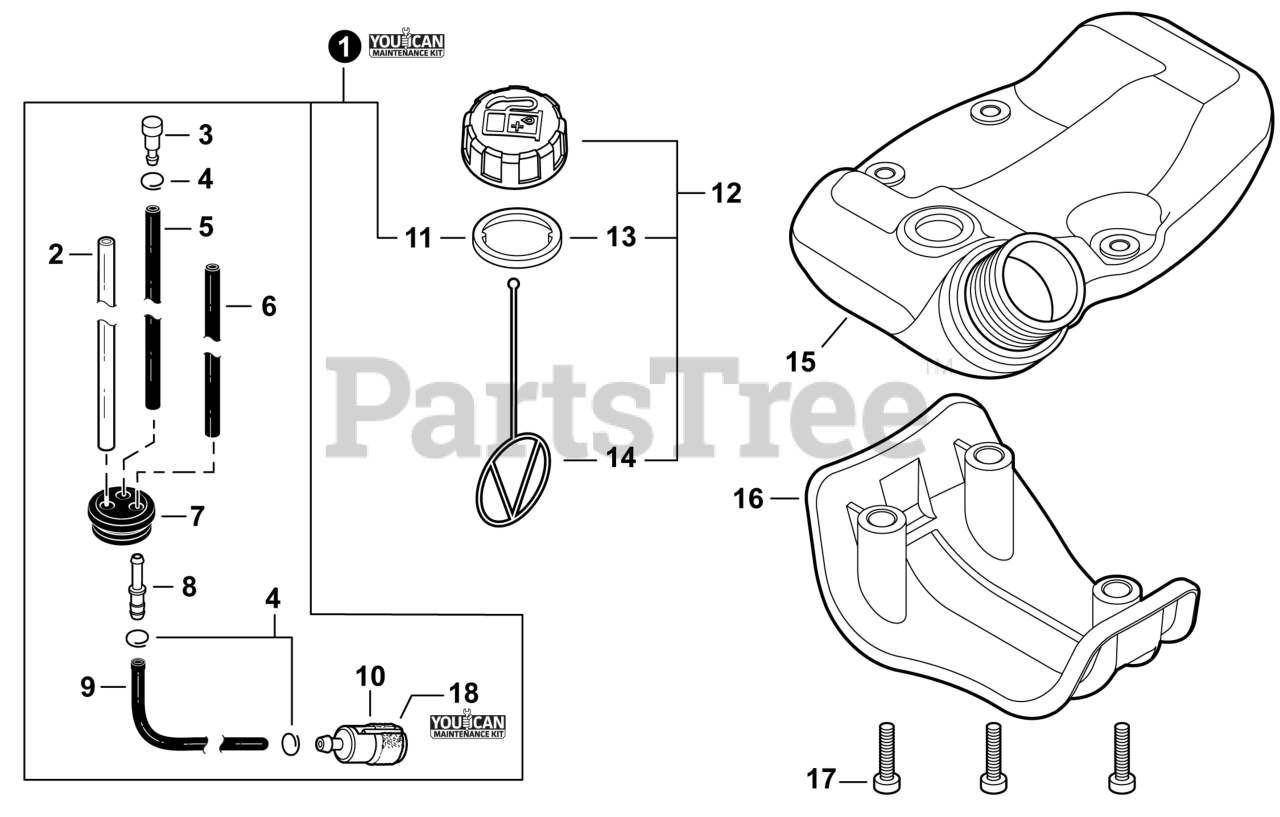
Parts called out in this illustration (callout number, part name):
1	FUEL SYSTEM KIT - YOUCANT
2	PIPE, FUEL 3x6x80 YELLOW
3	VENT ASSY
5	PIPE, FUEL 3x5x90 BLACK
6	PIPE, FUEL 3x5.5x74 BLACK
7	GROMMET, FUEL 5
8	CONNECTOR, PIPE 5x3.5
9	PIPE, FUEL 3x5x110 BLACK
10	FILTER, FUEL
11	GASKET, FUEL CAP
12	CAP ASSY, FUEL
13	GASKET, FUEL CAP
14	CONNECTOR, CAP L= 123
15	TANK ASSY, FUEL
16	GUARD, FUEL TANK
17	BOLT, TORX 5x25
18	TUNE-UP KIT - YOUCANT
